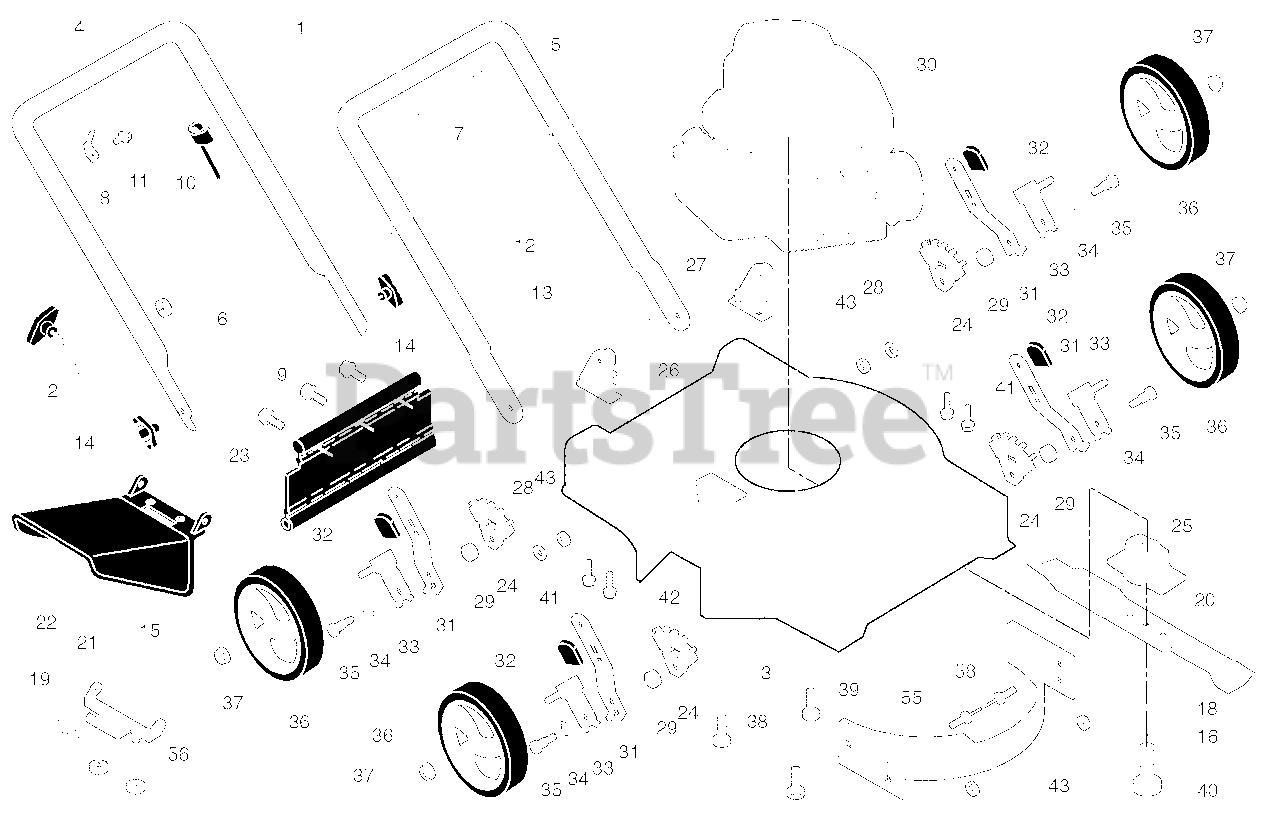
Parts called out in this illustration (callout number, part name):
1	Control Bar
2	Rope Guide
4	Upper Handle
5	Lower Handle
7	Handle Bolt 5/16-18 x 1-3/4
8	Up-Stop Bracket
9	Hex Washer Head Screw #10-24 x 1/2
10	Engine Zone Control Cable
11	Screw
12	Wire Tie
13	Hairpin Cotter
14	Knob, Handle
15	Discharge Guard
16	Helical Lock Washer 3/8
18	Hardened Washer
19	Torsion Spring
20	Blade, 20"
21	Hinge Deflector
22	Hinge Rod
23	Rear Deflector
24	Wheel Adjusting Bracket
25	Blade Adapter
26	Handle Bracket Assembly, RH
27	Handle Bracket Assembly, LH
28	Washer, Flat
29	Spacer
31	Selector Spring
32	Selector Knob
33	Axle Arm Assembly
34	Washer, Curved, Cylindrical
35	Shoulder Bolt
36	Wheel and Tire Assembly
37	Nut, Hex
38	Hex Head Thread Rolling Screw 3/8-16 x 1-1/8
39	Lawn Mower Housing
40	Hex Head Screw 3/8-24 x 1-3/8 Grade 8
41	Thread Cutting Screw 5/16-18 x 3/4
42	Danger Decal
43	Locknut, Hex 3/8-16
56	Locknut, Hex 1/4-20
58	Pop Rivet
58	Operator's Manual, English
58	Operator's Manual, Spanish
58	Repair Parts Manual, English
